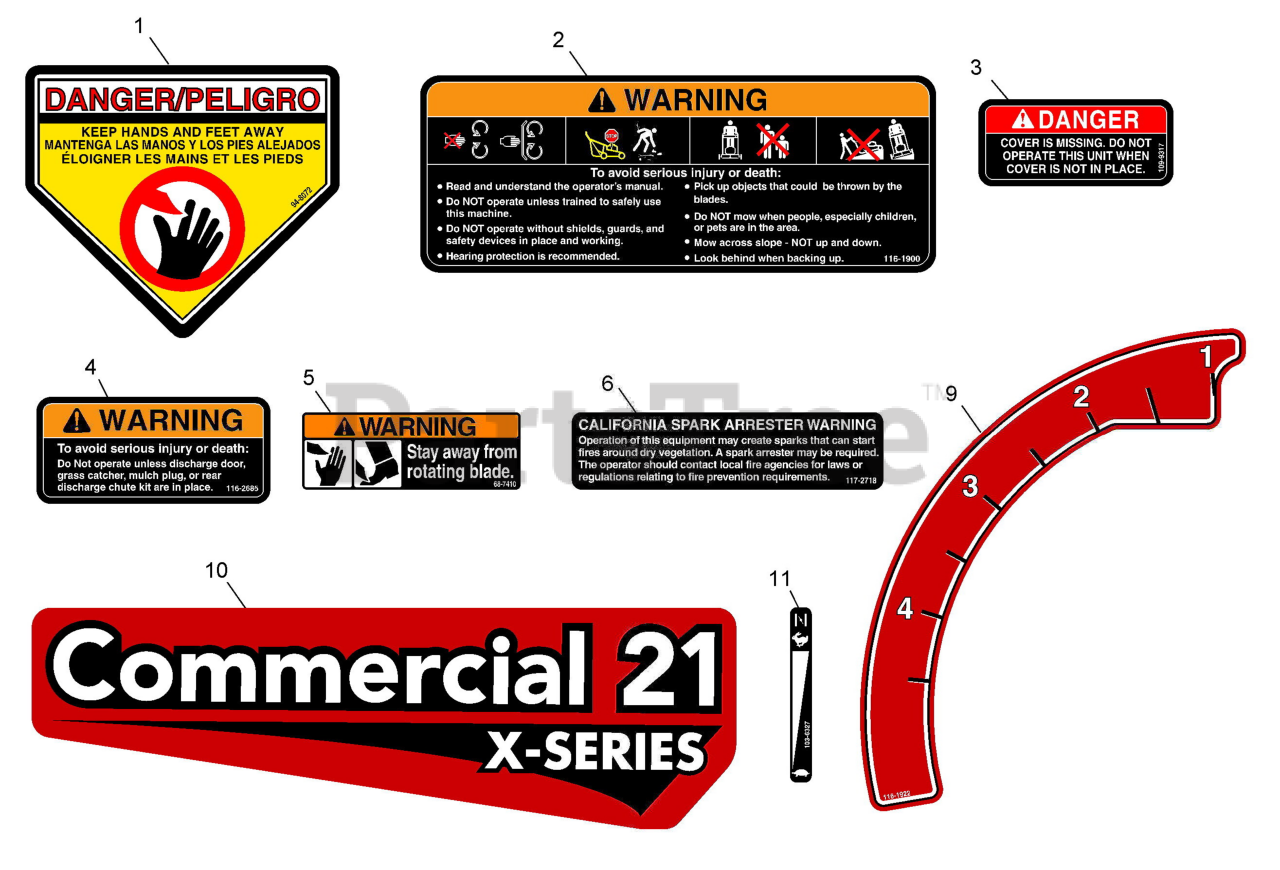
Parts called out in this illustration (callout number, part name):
1	DECAL-DANGER
2	DECAL-WARNING
3	DECAL-COVER MISSING
4	DECAL-WARNING DOOR SM
5	DECAL-BLADE
6	DECAL-ARRESTER, SPARK
9	DECAL-HEIGHT OF CUT
10	DECAL-COMM 21 X-SERIES
11	DECAL,THROTTLE/CHOKE
